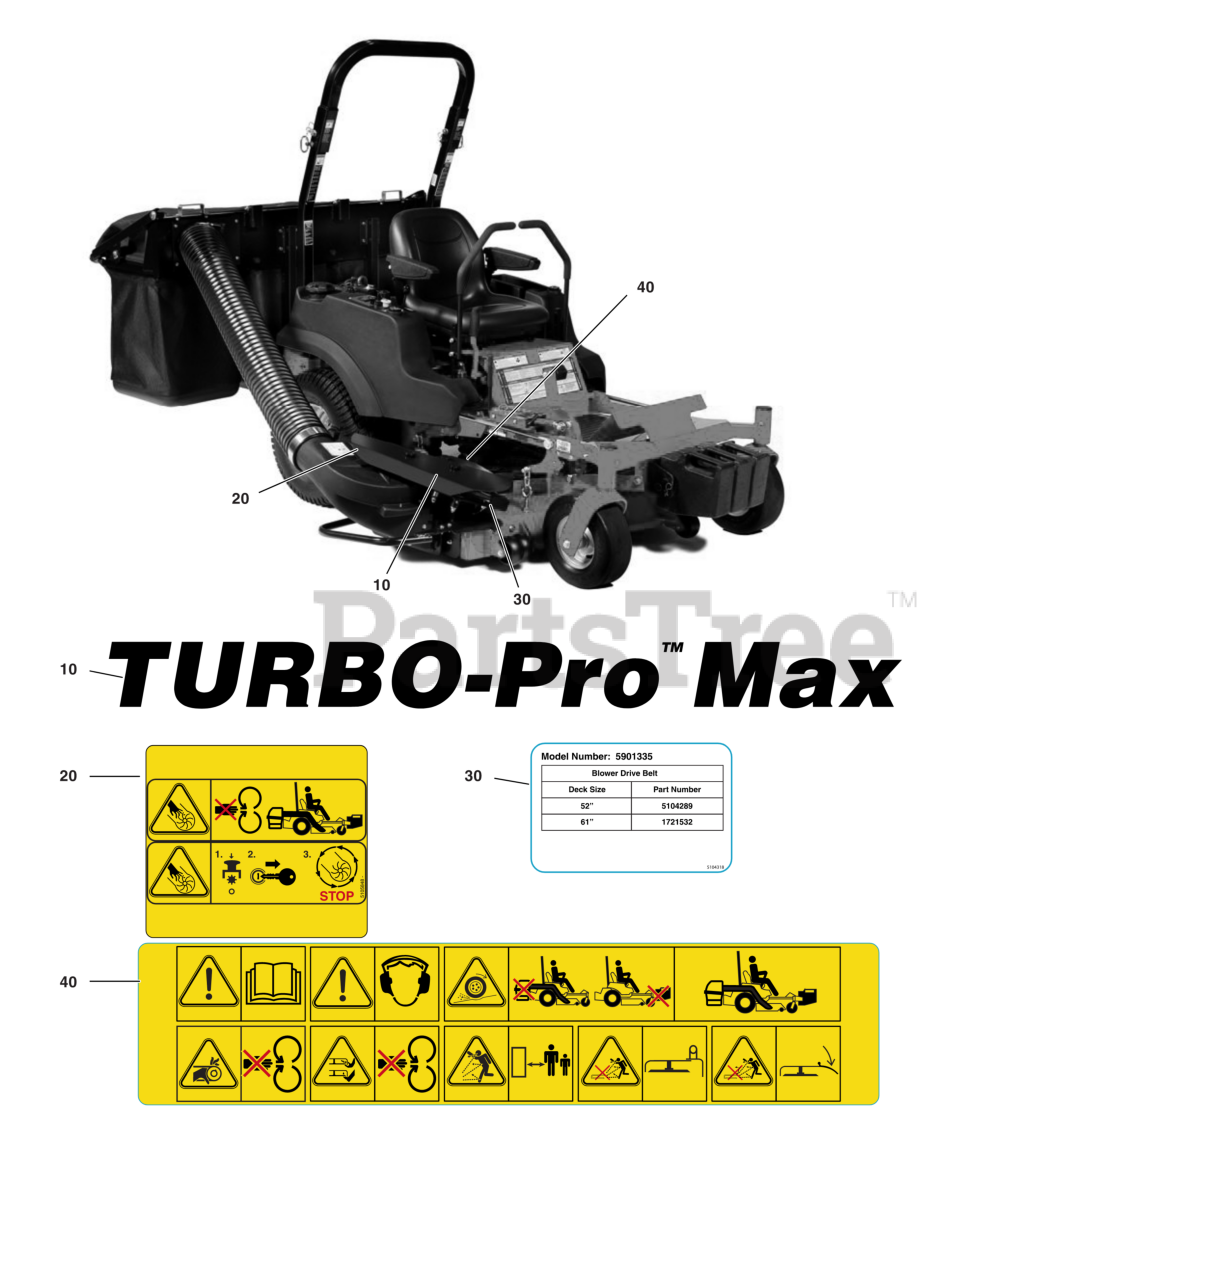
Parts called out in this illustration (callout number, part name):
10	DECAL, MODEL
30	DECAL, MODEL
40	DECAL, BLOWER, MAIN
